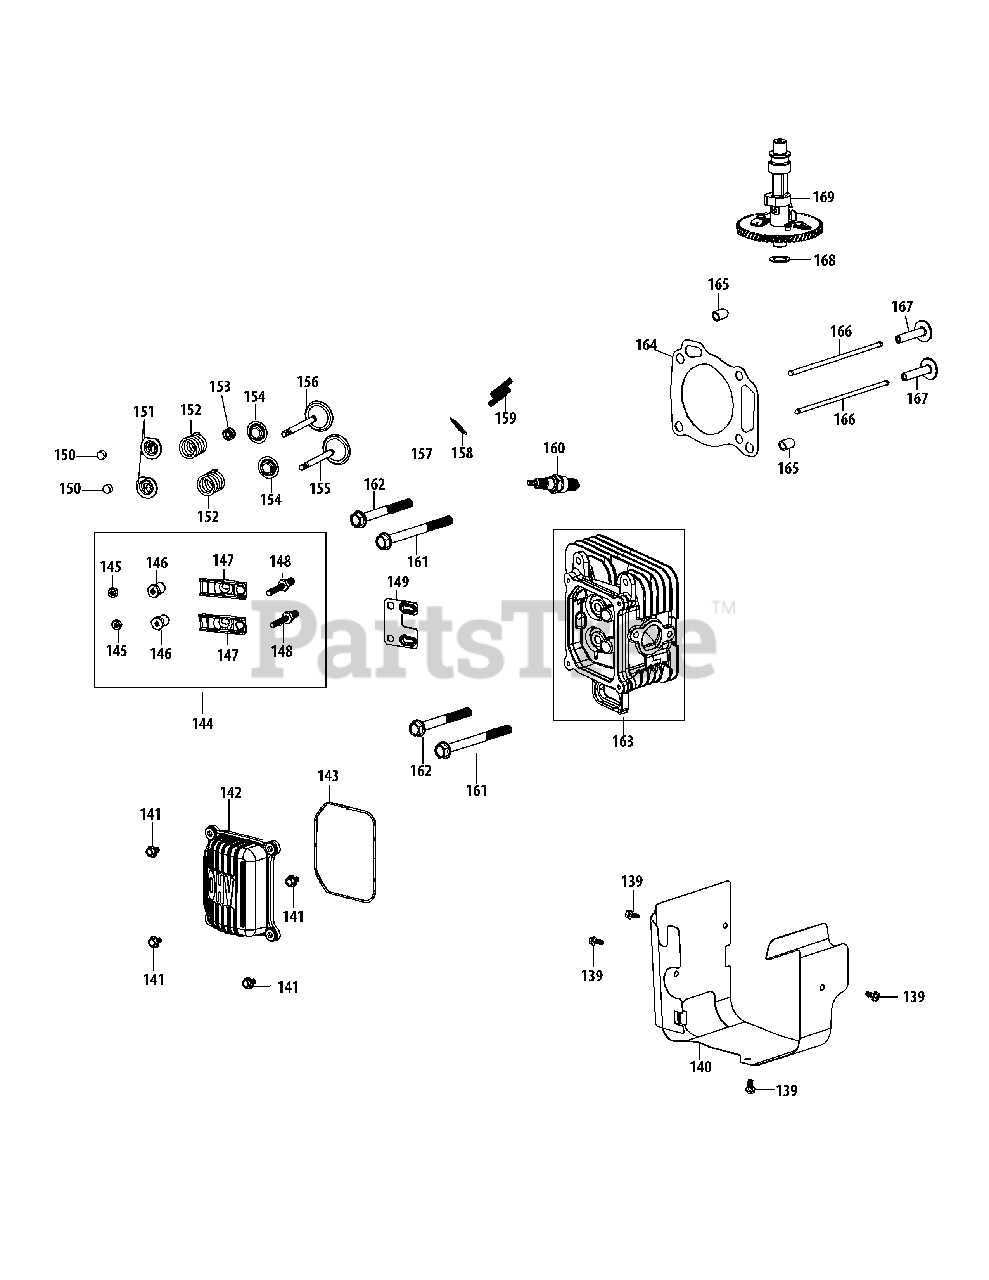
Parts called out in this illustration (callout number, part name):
139	Bolt M5×10
141	Valve Cover Bolt
142	Valve Cover
143	Valve Cover Ring
144	Rocker Arm Assembly
146	Fulcrum Nut
147	Rocker Arm
148	Rocker Arm Stud
149	Push Rod Guide
150	Exhaust Valve Adjuster
151	Exhaust Valve Spring Retainer
152	Valve Spring
153	Intake Valve Seal
154	Valve Spring Retainer
158	Exhaust Pipe Gasket
159	Muff Stud M8×47
159	Muffler Stud Assembly
160	Spark Plug/F6Rtc
161	Bolt M10×1.25×85
162	Bolt /M10×1.25×65
163	Cylinder Head
164	Cylinder Head Gasket
165	Cylinder Head Dowel 12×16
166	Push Rod Kit
167	Tappet
168	Camshaft Thrust Washer
169	Camshaft Assembly
